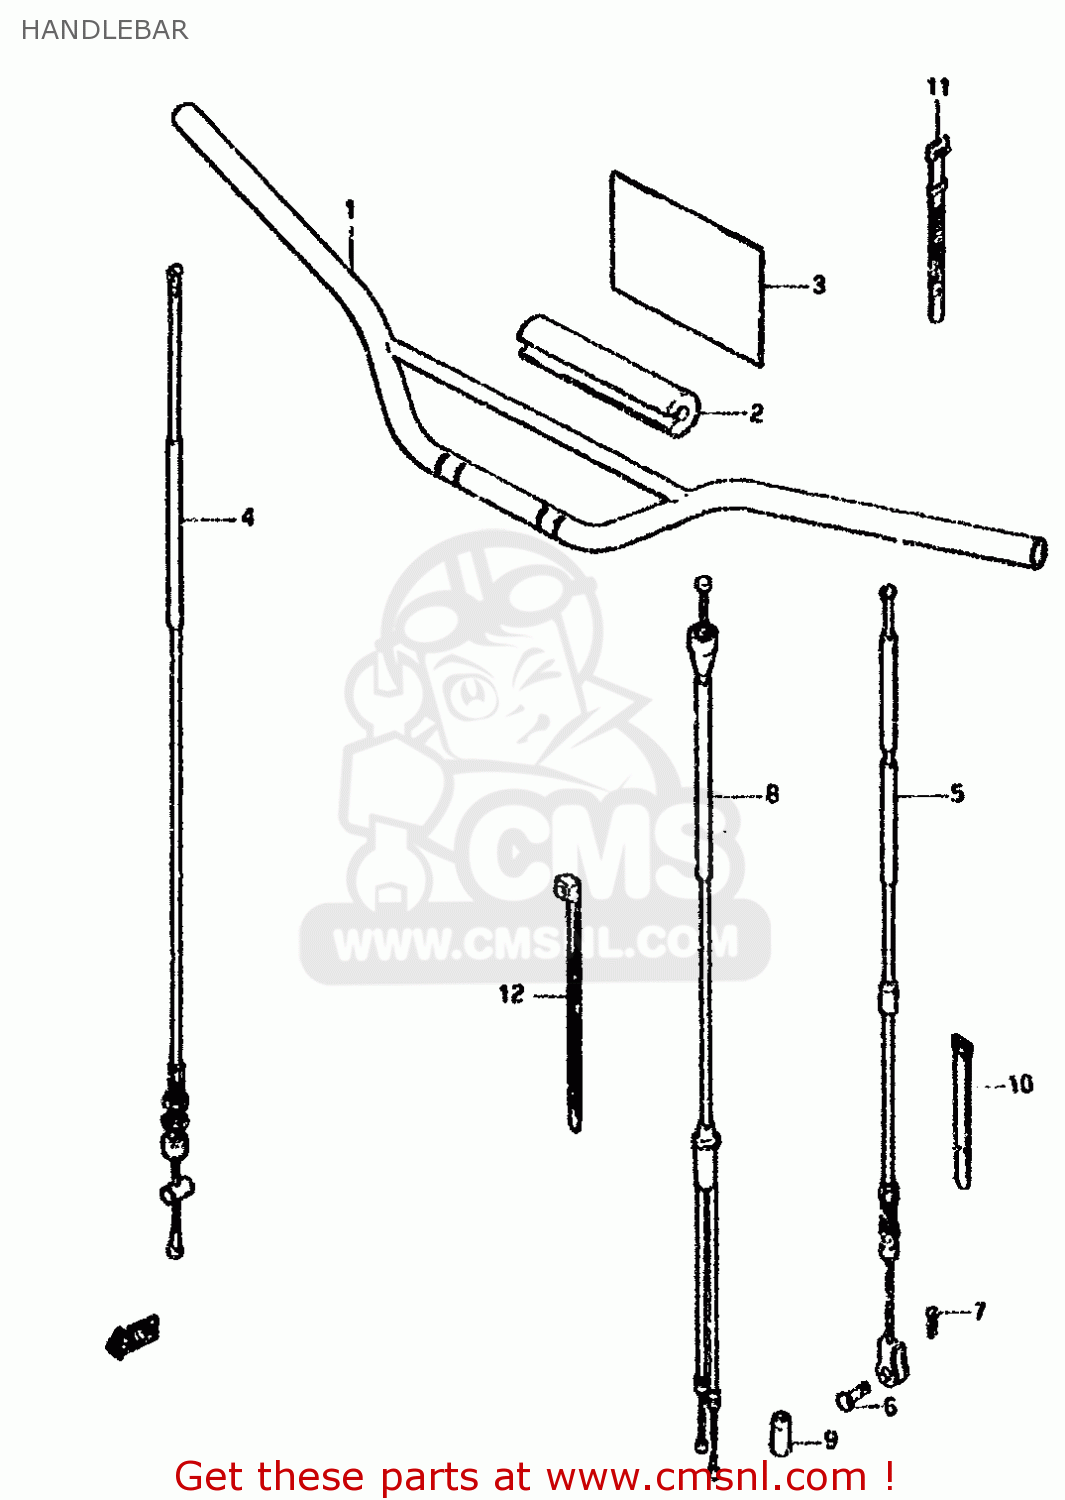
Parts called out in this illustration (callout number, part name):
1	HANDLEBAR
2	PAD,CROSSBAR
3	COVER,CROSS BAR PAD
4	CABLE,FR BRAKE
5	CABLE ASSY,CLUTCH
6	PIN(L:13)
7	PIN
8	CABLE ASSEMBLY,THROTTLE
9	SEAL,DUST(7X18X30)
10	CLAMP
11	CLAMP(L:145)
12	CLAMP L:165
